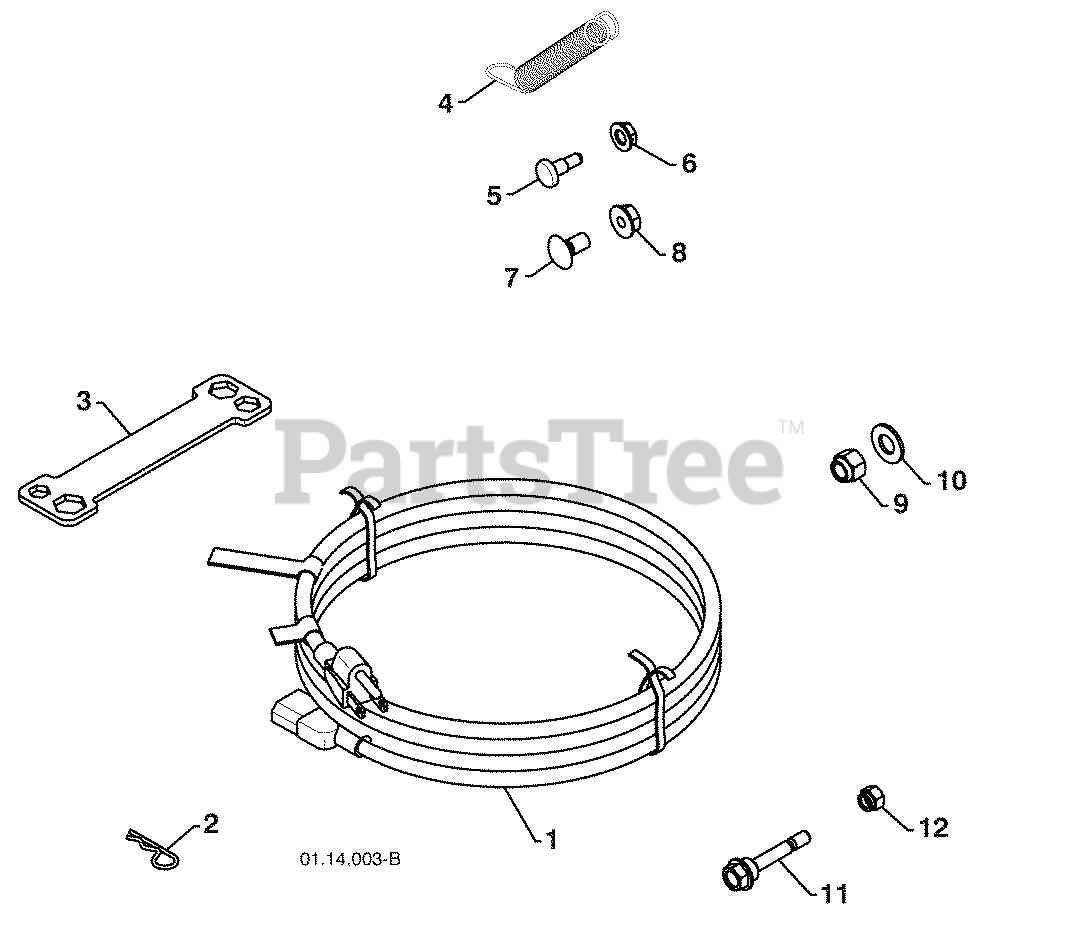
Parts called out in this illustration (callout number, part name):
1	POWER CORD
2	RETAINER PIN
3	WRENCH
4	REMOTE SPRING
5	SHOULDER BOLT 1/4-20
6	NYLON WASHER 1/4-20
7	LOCKNUT 1/4-20
8	CARRIAGE BOLT 5/16-18 X 5/8
9	LOCKNUT 5/16-18
10	LOCKNUT 3/8-16
11	SHEAR BOLT 1/4-20 X 1-3/4
12	LOCKNUT 1/4-20
